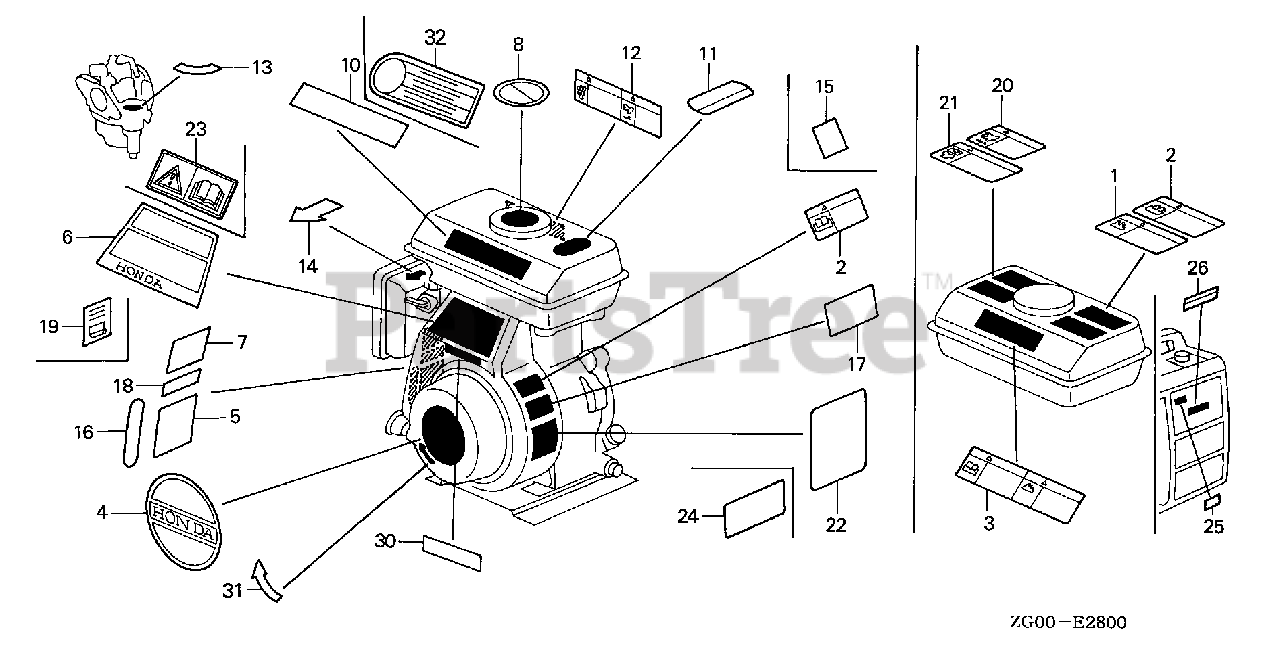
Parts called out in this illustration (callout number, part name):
11	MARK, CAUTION
14	MARK, CHOKE
16	MARK, THROTTLE
22	MARK, OIL CAUTION
31	MARK, STARTING
32	MARK, CAUTION (ENGLISH/FRENCH)(SPANISH)
